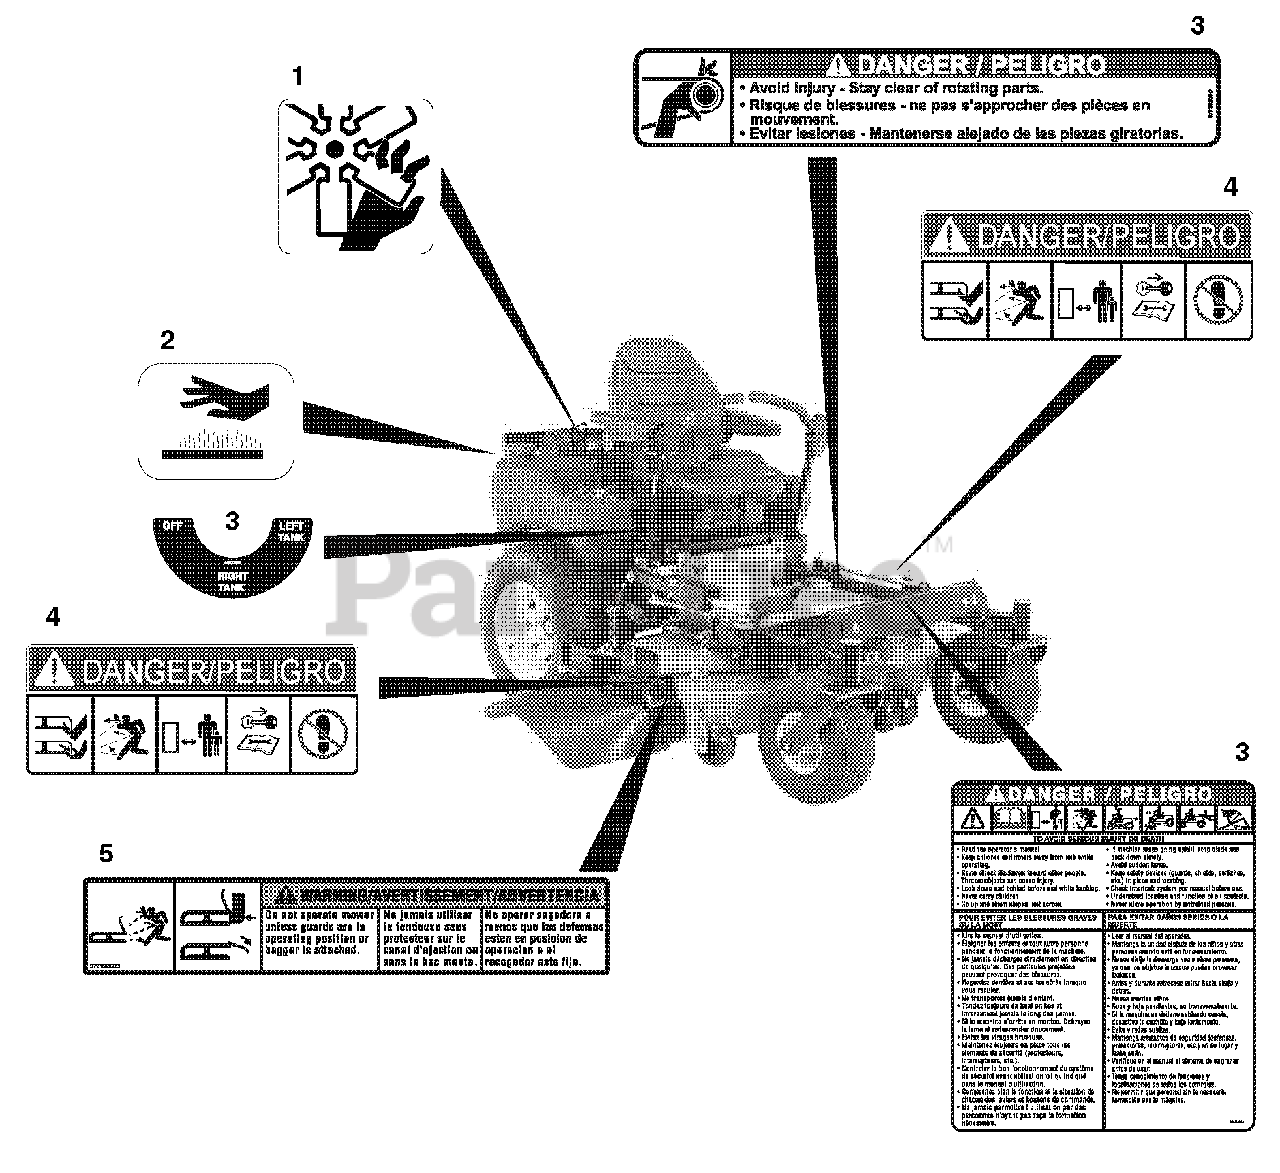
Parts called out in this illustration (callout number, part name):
1	Decal, Danger Fan (991029, 030, 032)
2	Decal, Hot Surface
3	Set, Decal-Common Danger/Fuel
4	Decal, Mower Pan Head Danger
5	Decal, Warning
